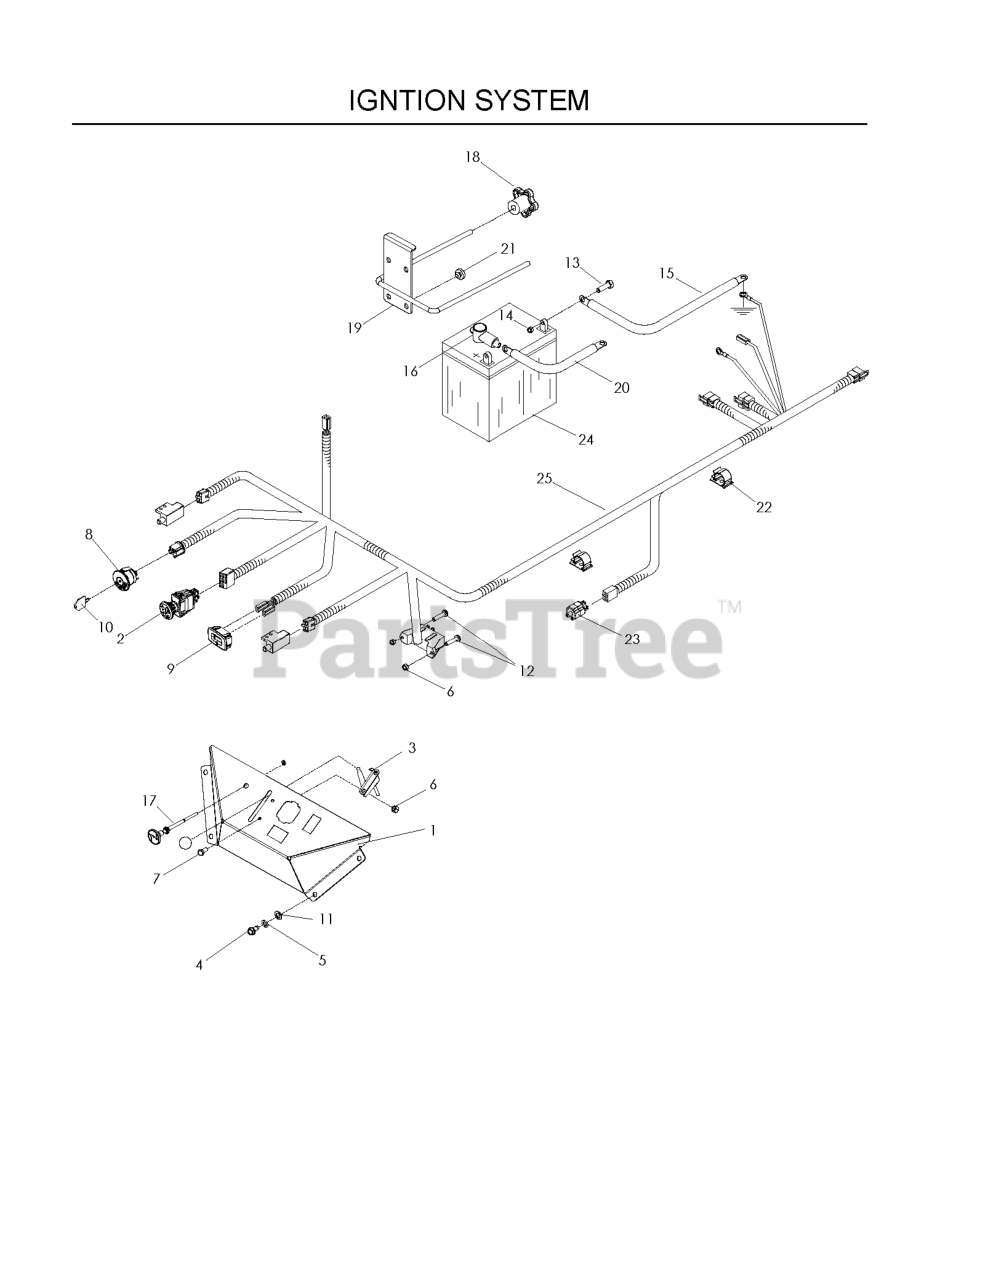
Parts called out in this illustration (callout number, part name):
1	CONSLE, ORANGE
2	SWITCH, PTO 10 AMP
3	THROTTLE CONTROL W/BALL KNOB
4	SCREW 1/4 X 5/8
5	LOCKWASHER 1/4"
6	NUT 10-24 NYLOC
7	HCS #10-24 X 1/2
8	RP IGNITION SWITCH
9	HOUR METER
10	KEY
11	WASHER 1/4 FLAT
12	SCREW, #1--24 X 1/2 SLOTTED
13	HCS 5/16C X 3/4
14	NUT 5/16 NYLOC
15	CABLE-NEGATIVE
17	CONTROL-CHOKE 51"
19	BATTERY HOLD DOWN
20	POST.CABLE LONG
21	GROMMET, BUMPER
22	PUSH-MOUNT WIRE CLIP
23	SWITCH, BRAKE 3P
24	BATTERY, 12 V 330 AMP
25	HARNESS, WIRING LZ/IZ
